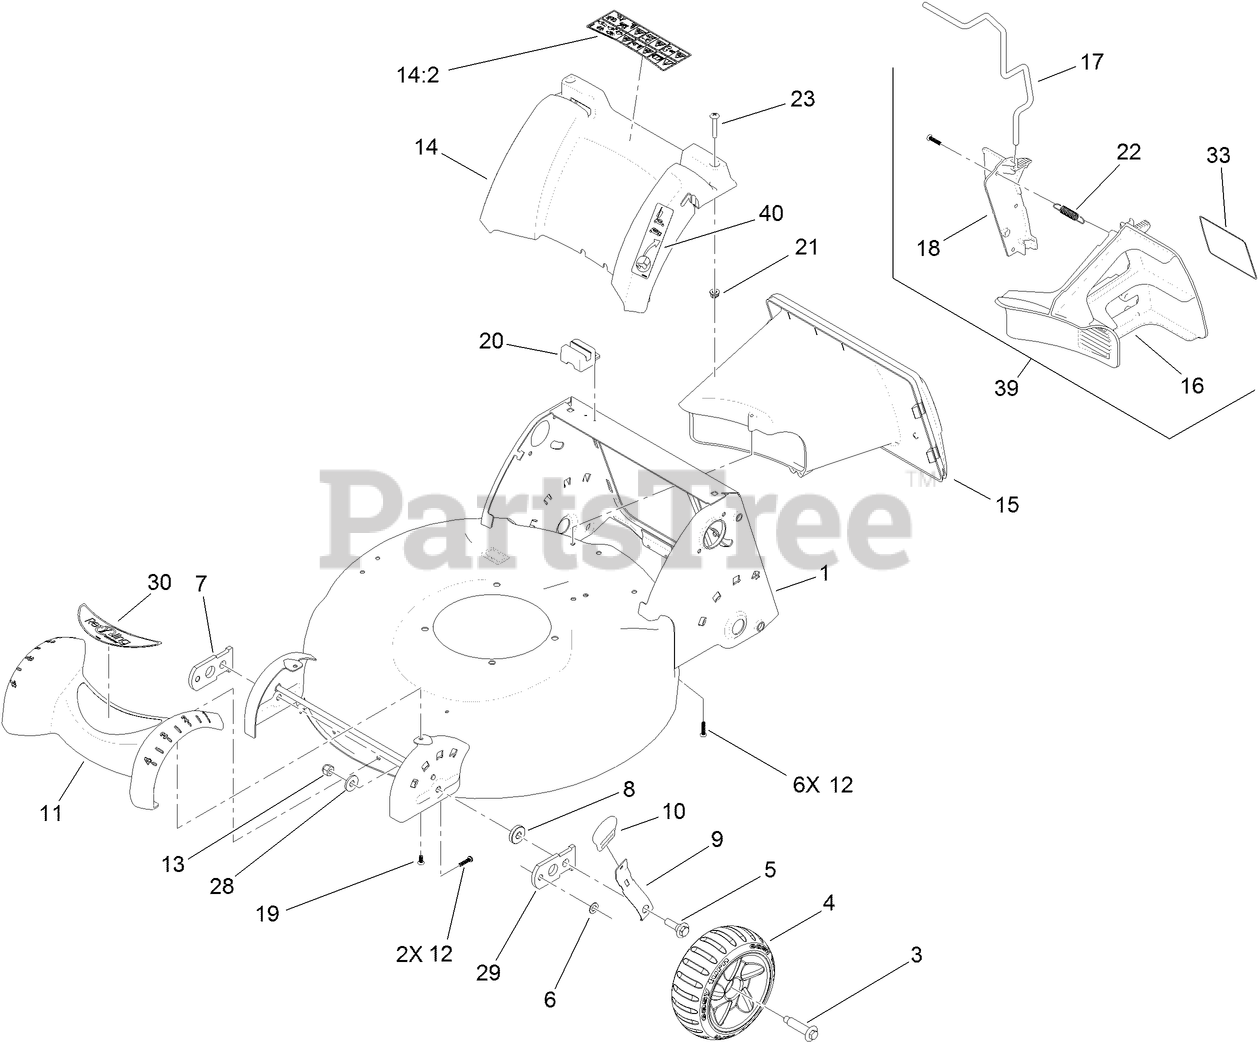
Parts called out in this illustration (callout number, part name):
1	DECK ASM
3	BOLT-SHOULDER
4	7 INCH WHEEL AND TIRE ASM
5	SCREW-SHOULDER, HWH
6	WASHER
7	ARM-PIVOT, RH
8	WASHER
9	ARM-SPRING
10	KNOB-HOC
11	COVER-FRONT
12	SCREW-PLASTITE
13	NUT-LOCK, NI
14	REAR COVER ASM
14:2	DECAL-WARNING
15	TUNNEL
16	PLUG-MULCH, LH
17	LATCH-PLUG, MULCH
18	PLUG-MULCH, RH
19	SCREW-PLASTITE
20	MODULE-SWITCH
21	NUT-CLIP
22	SPRING-EXTENSION
23	SCREW-PTH
28	WASHER-HARDENED
29	ARM-PIVOT, LH
30	DECAL-FRONT (CE)
33	DECAL-PLUG, MULCH
39	MULCH PLUG ASM
40	DECAL-QUICK STOW
